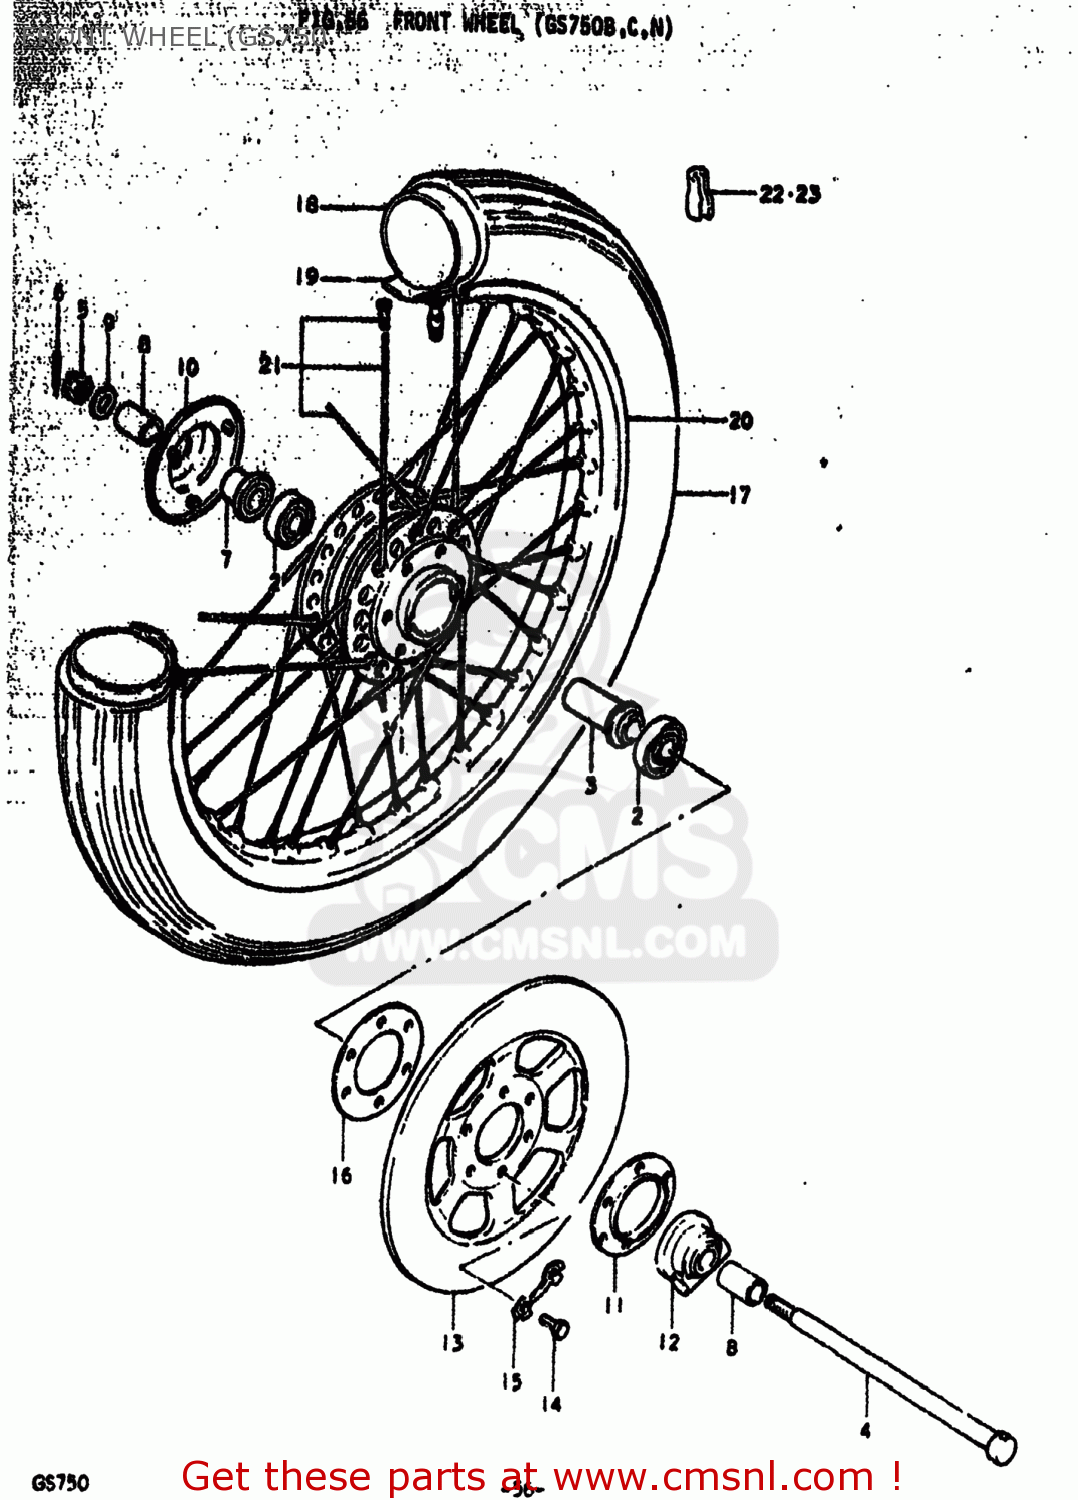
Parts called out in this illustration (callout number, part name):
1	DRUM,FRONT HUB
2	BEARING
3	SPACER,FR HUB BEARING
4	AXLE,FRONT
5	NUT 12MM
6	COTTER PIN
7	SPACER,FR AXLE,R
8	SPACER(15X22X30)
9	WASHER
10	COVER,FR HUB,R
11	DUST SEAL
12	BOX ASSEMBLY,SPEEDOMETER GEAR
13	DISC,BRAKE
14	BOLT(8X30)
15	WASHER
16	SHIM,BRAKE DISC
17	TIRE,FRONT
18	TUBE,INNER
19	PROTECTOR,WHL INR TUBE
20	RIM,FR WHEEL
21	SPOKE SET,FRONT
22	BALANCER,WHEEL (B)
23	BALANCER,WHEEL (30G)
